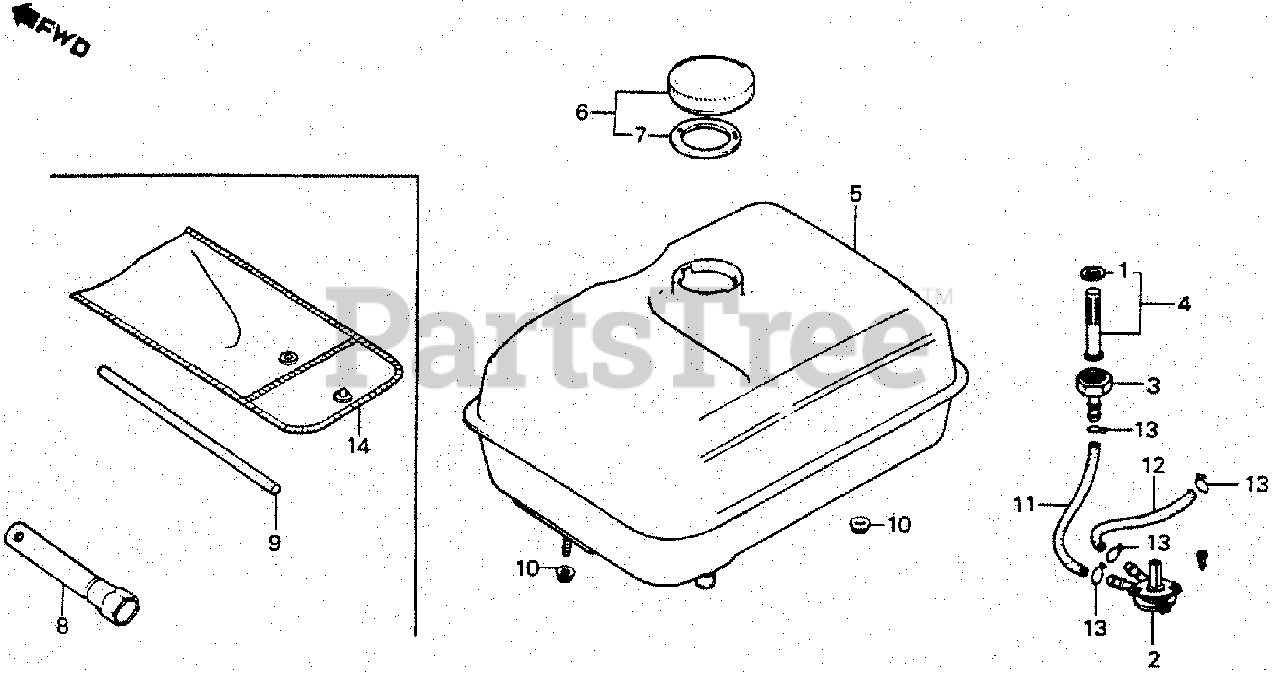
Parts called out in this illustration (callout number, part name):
1	GASKET SET, VALVE
2	PETCOCK ASSY. (NOT AVAILABLE)
3	JOINT, FUEL
4	SCREEN SET
5	TANK, FUEL *NH31* (MCKINLEY WHITE)
6	CAP, FUEL FILLER
7	GASKET, FUEL FILLER CAP
8	WRENCH, SPARK PLUG (NOT AVAILABLE)
9	HANDLE, BOX WRENCH (NOT AVAILABLE)
10	NUT, FLANGE (6MM)
11	BULK HOSE, FUEL (4.5X3000) (4.5X90)
12	BULK HOSE, FUEL (4.5X3000) (4.5X130)
13	CLIP, TUBE (B8)
